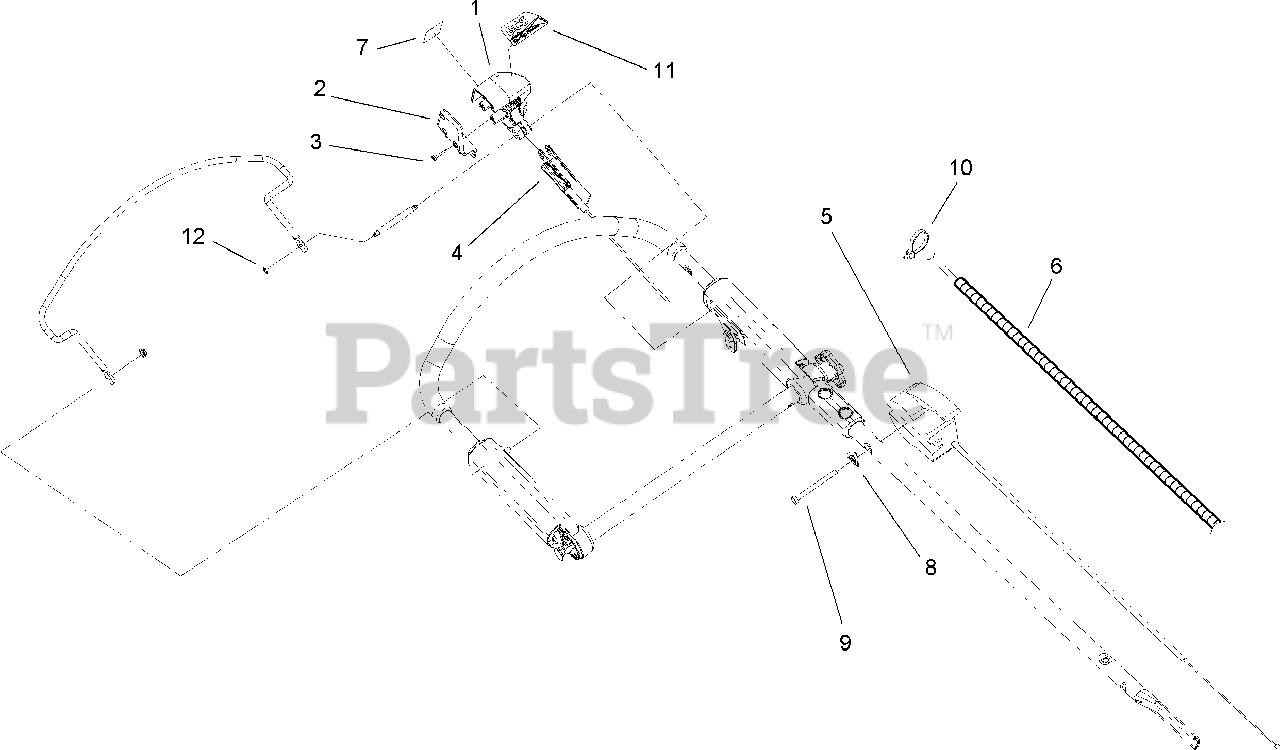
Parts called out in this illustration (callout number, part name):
1	PIVOT ASM
2	COVER-SWITCH
3	SCREW-PPH
4	CABLE-BRAKE
5	CABLE-THROTTLE
7	DECAL-BLADE, BBC
9	SCREW-HH
10	STRAP-TIE
11	DECAL-CONTROL, BLADE
12	RING-RETAINING
